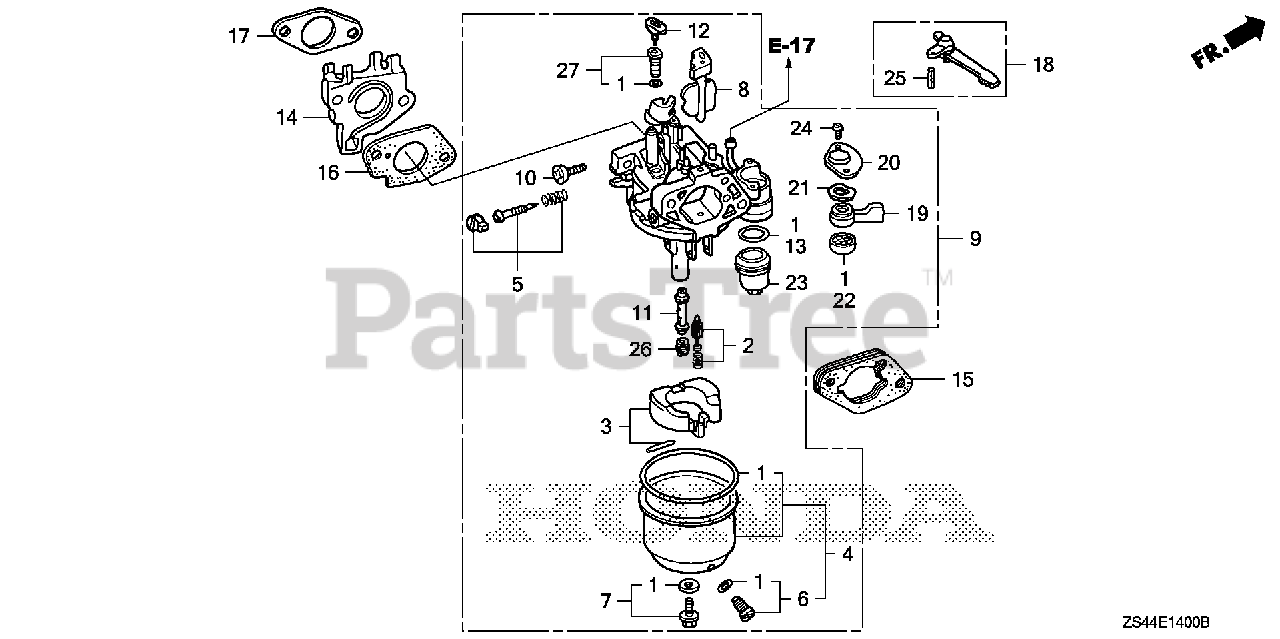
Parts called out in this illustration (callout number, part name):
1	GASKET SET (INCLUDES 16173-001-004)
2	VALVE SET, FLOAT
4	CHAMBER SET, FLOAT (CARBURETOR NO.)
5	SCREW SET, PILOT
6	SCREW SET, DRAIN
7	SCREW SET
9	CARBURETOR ASSY. (BE70E B)
10	SCREW, THROTTLE STOP
11	NOZZLE, MAIN
12	COLLAR, SETTING
13	GASKET, FUEL STRAINER CUP
14	INSULATOR, CARBURETOR
15	SPACER, CARBURETOR
16	GASKET, CARBURETOR
17	GASKET, INSULATOR
18	LEVER, CHOKE (STD)
19	LEVER, PETCOCK (CARBURETOR NO.)
20	PLATE, LEVER SETTING
21	SPRING, PETCOCK LEVER
22	GASKET, PETCOCK
23	CUP, FUEL STRAINER
24	SCREW, PAN (3X6)
25	PIN, SPRING (2X12)
26	JET, MAIN (#82)
26	JET, MAIN (#85)
26	JET, MAIN (#88)
27	JET SET, PILOT (#40)
